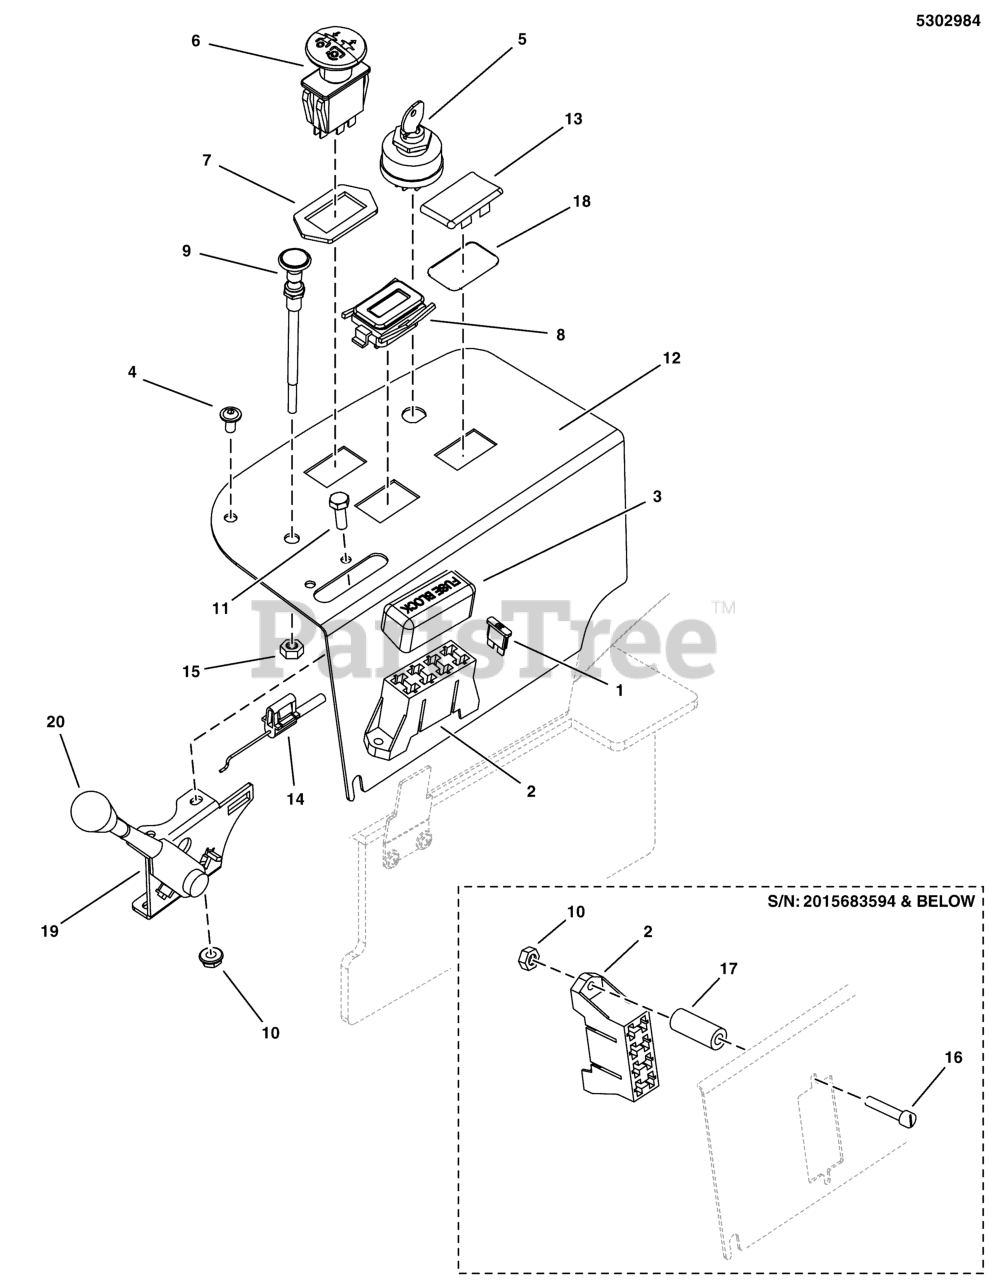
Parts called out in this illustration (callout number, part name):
1	FUSE, ATO 20 AMP
2	FUSE, BLOCK
3	COVER, VINYL FUSEBLOCK
4	SCREW, 1/4-20 X 1/2" ALLEN BH
5	SWITCH, IGNITION, 6 POST
6	SWITCH, BLADE ENGAGEMENT
7	RING, SWITCH RETAINER
10	NUT, #10-24 HEN NYLON LOCK
11	SCREW, #10-24 X 3/4"
13	PLUG, .820X1.44 HOLE, BLACK PLASTIC
15	NUT, 3/8 - 24 HEX
16	SCREW, #10-24 X 2" ROUND PHILLIPS
17	SPACER, .20 X .38 X 1.25
18	O-RING, 7/8" ID X 1/16"
19	LEVER, THROTTLE CONTROL, HEAVY-DUTY
20	THROTTLE CONTROL HANDLE/KNOB
